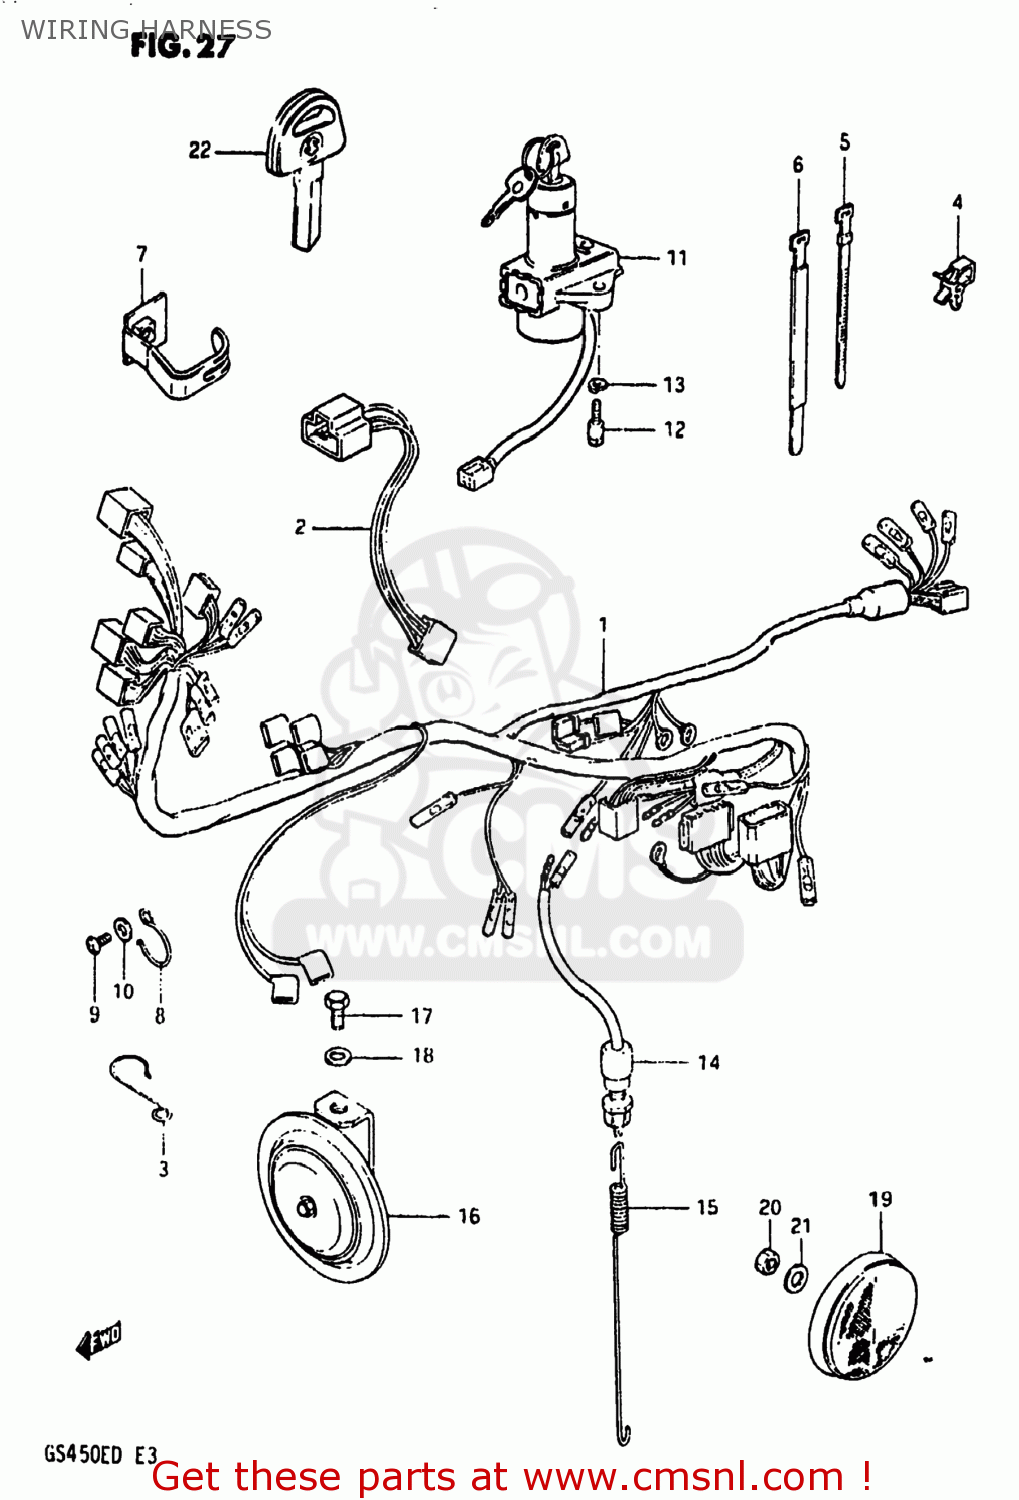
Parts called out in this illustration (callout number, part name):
1	HARNESS,WIRING
2	LEAD WIRE,HEADLAMP
3	CLIP,WIRING HARNESS
4	CLIP
5	CLAMP(L:120)
6	CLAMP
7	CLAMP,WIRING HARNESS
8	GUIDE,WIRING HARNESS
9	SCREW 6X12
10	WASHER
11	SWITCH ASSY,IGNITION
12	BOLT
13	LOCK WASHER
14	SWITCH ASSEMBLY,STOP LAMP
15	SPRING
16	HORN ASSEMBLY
17	BOLT 8X12
18	WASHER
19	REFLEX REFLECTOR,RR
20	NUT
21	WASHER
22	KEY,BLANK
